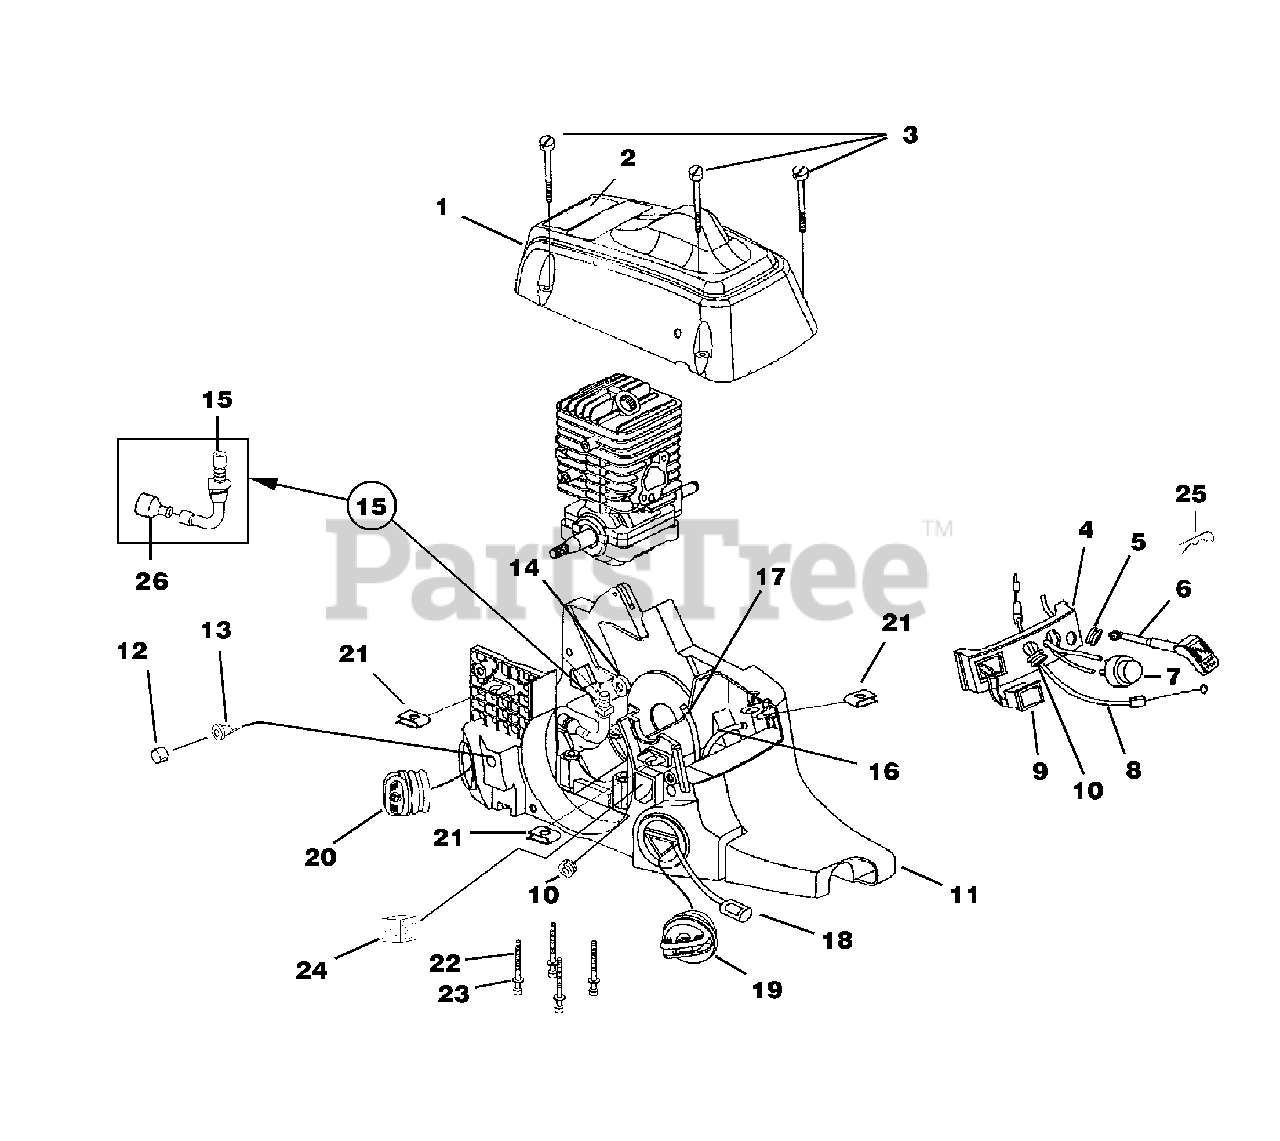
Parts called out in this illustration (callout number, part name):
1	Cylinder Cover Kit
2	Safety Decal
3	Screw-Slotted Pan Hd.
4	Control Panel
5	Grommet
6	Rod, Choke
7	Bulb, Air Purge
8	Throttle Cable
9	Switch, Rocker
10	Grommet - Split
11	Engine Housing
12	Element, Filter (Bronze)
13	Duck Bill Valve
14	Oil Outlet Grommet
15	Oil Intake Tube
16	Rubber Tubing (5 1/2")
17	Rubber Tubing (8 1/2")
18	Fuel Filter
19	Fuel Cap w/ Retainer
20	Oil Cap w/ Retainer
21	Speed Nut ("U-Type")
22	Screw, Cap-Socket Hd. (10-24 x 2")
23	Washer
24	Pre Filter
25	Spring Clip (Choke Rod)
26	Oil Filter
